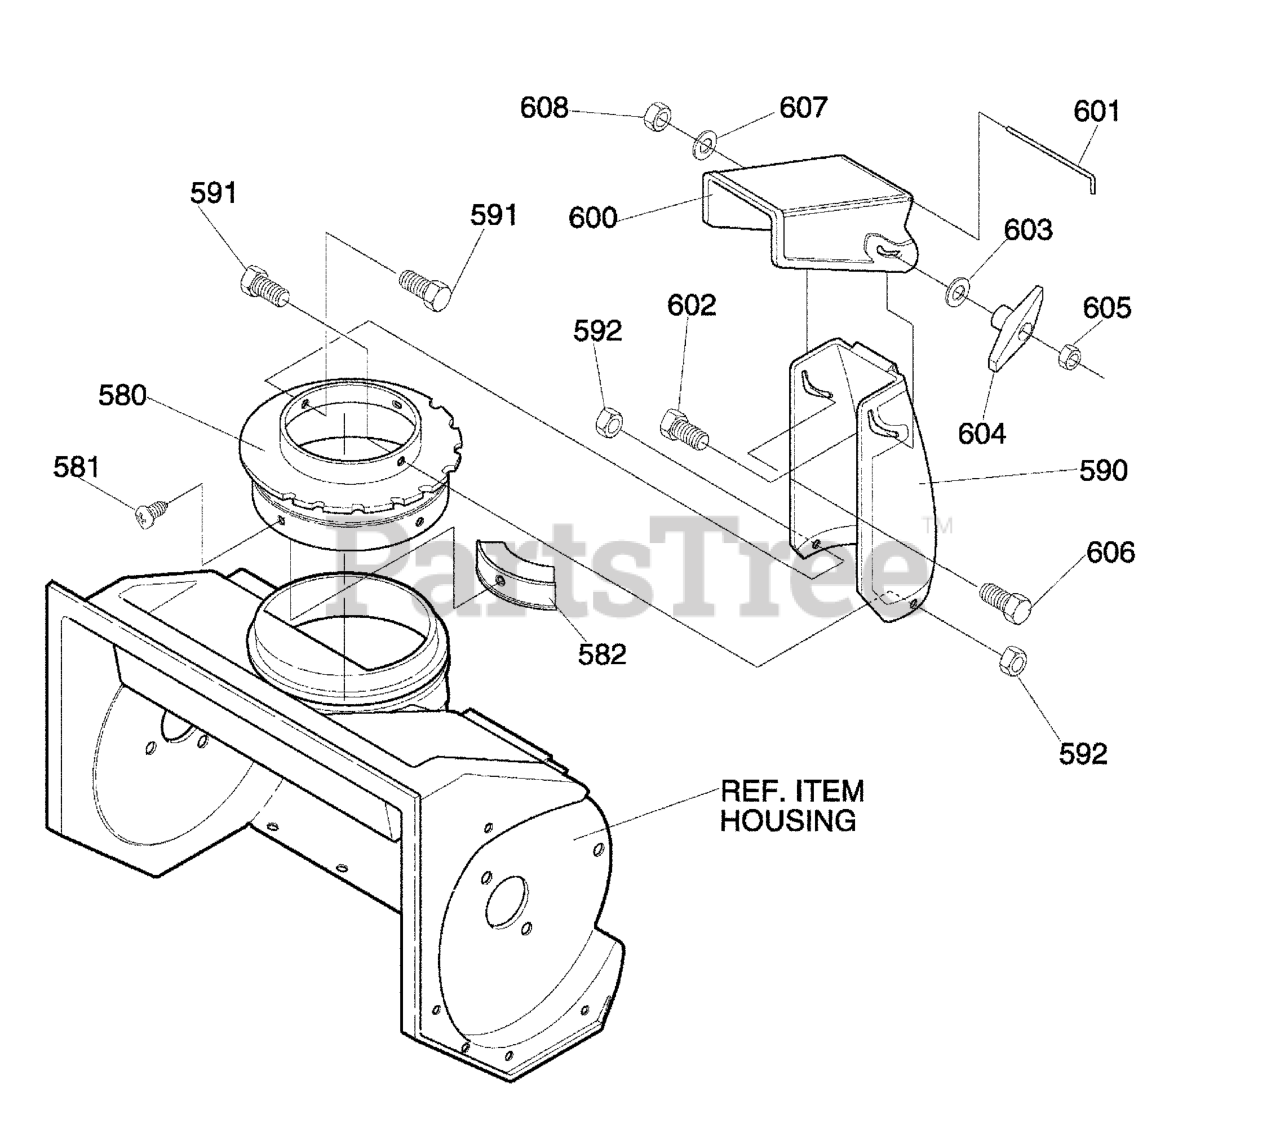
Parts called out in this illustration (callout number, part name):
580	RING, CHUTE
581	SCREW, #10X.50 HHTAPPST
582	GUIDE, CHUTE
590	CHUTE, LOWER
591	SCREW 1/4-20X.50
592	NUT, CNTRLK 1/4-2
600	CHUTE, UPPER
601	WIRE, HINGE
602	BOLT, 5/16-18X1.25 CARR.
603	WASHER, FLAT .349X.69X.066
604	KNOB, T
605	NUT, 5/16-18 REGHEX
606	SCREW, 5/16-18 x 0.75
607	WASHER, FLAT .349X.69X.066
608	NUT, 5/16-18 REGHEXCTRLK
